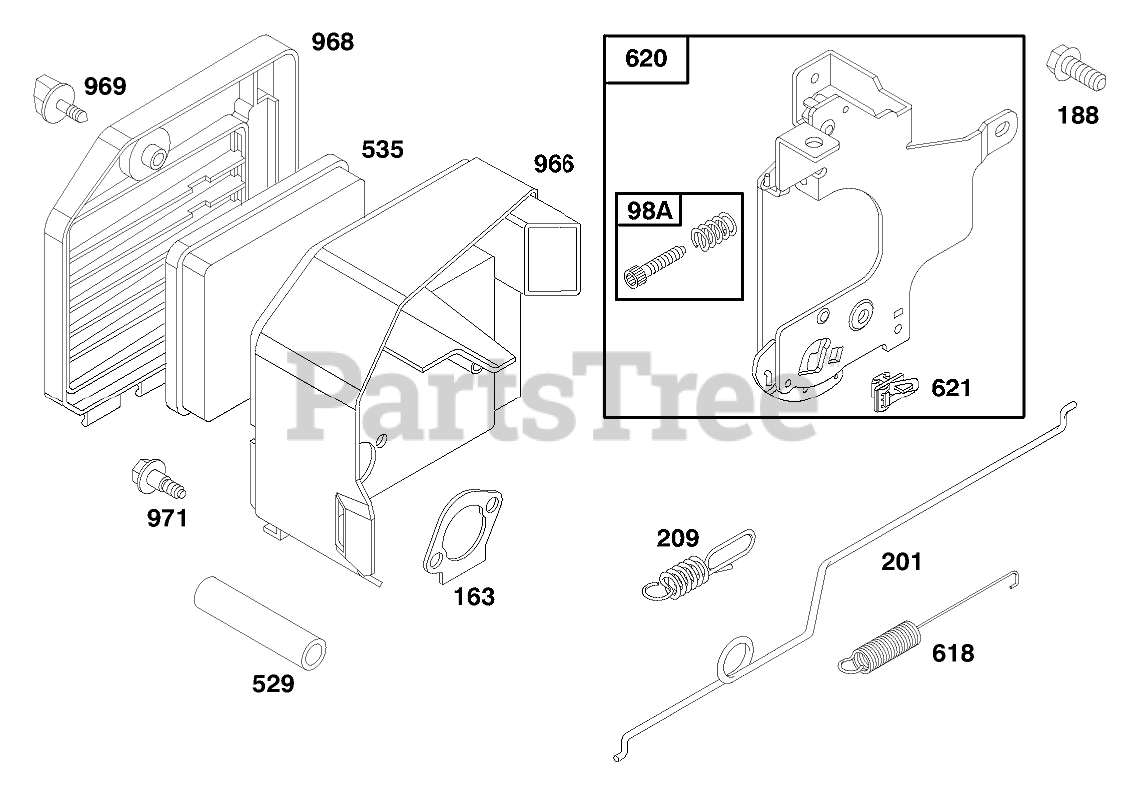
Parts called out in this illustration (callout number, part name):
98A	SPEED ADJUST. SCREW ASM
163	AIR CLEANER GASKET
188	Screw-Cap
201	GOVERNOR LINK
209	GOVERNOR SPRING
529	TUBE - BREATHER
535	FILTER ELEMENT
618	RETURN SPRING
620	CARBURETOR BRACKET
621	STOP SWITCH
966	AIR CLEANER BASE
968	AIR CLEANER COVER
969	AIR CLEANER SCREW
971	AIR CLEANER SCREW
